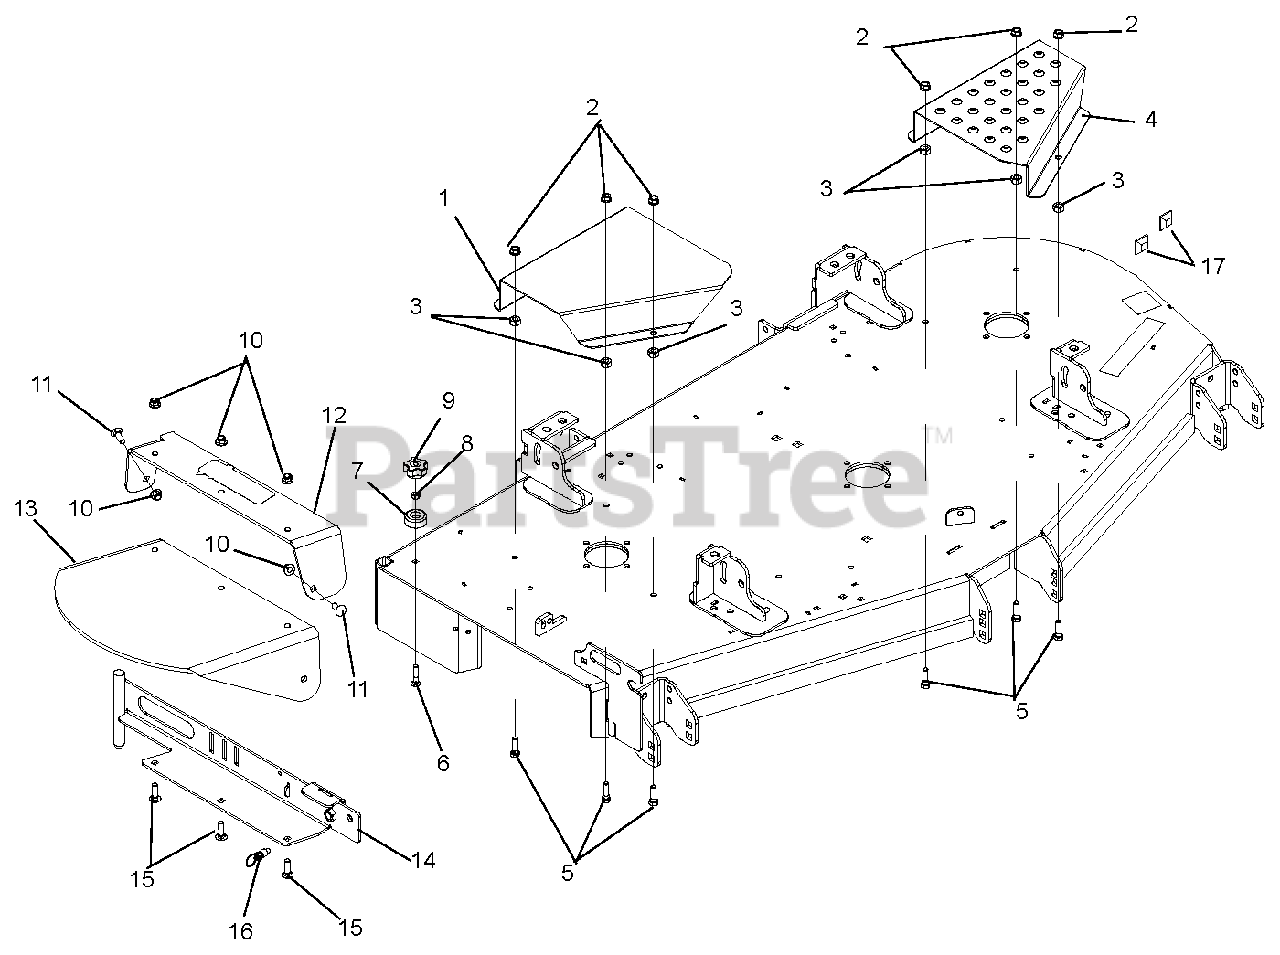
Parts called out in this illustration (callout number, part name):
1	Guard, Deck Belt, Right Hand 60" (992201, 203, 204, 198)
2	Nut, Spin Lock-Flange .375-16
3	Nut, Heavy Hex .38-16
4	Guard, Deck Belt, Left Hand 60" (992201, 203, 204, 198)
5	Bolt, Hex .38-16 x 1.25 Grade 5
6	Bolt, Round Head Square Neck .31-18 x 1.50 Grade 5
8	Nut, Locking-Center .31-18
9	Knob, Clamping, .312-18 Nyloc
10	Nut, Locking Nyloc Flange .38-16
11	Bolt, Round Head Square Neck .38-16 x 1.00 Grade 5
12	Support, Rubber Discharge Chute
13	Chute, Rubber Discharge
14	Discharge Chute Mounting Weldment (992200, 201, 203, 204, 205, 197, 198)
15	Bolt, Round Head Square Neck .38-16 x 1.25 Grade 5
16	Pull Pin, .50-13 Thread x .310 Diameter Plunger
17	Stop (992206)
